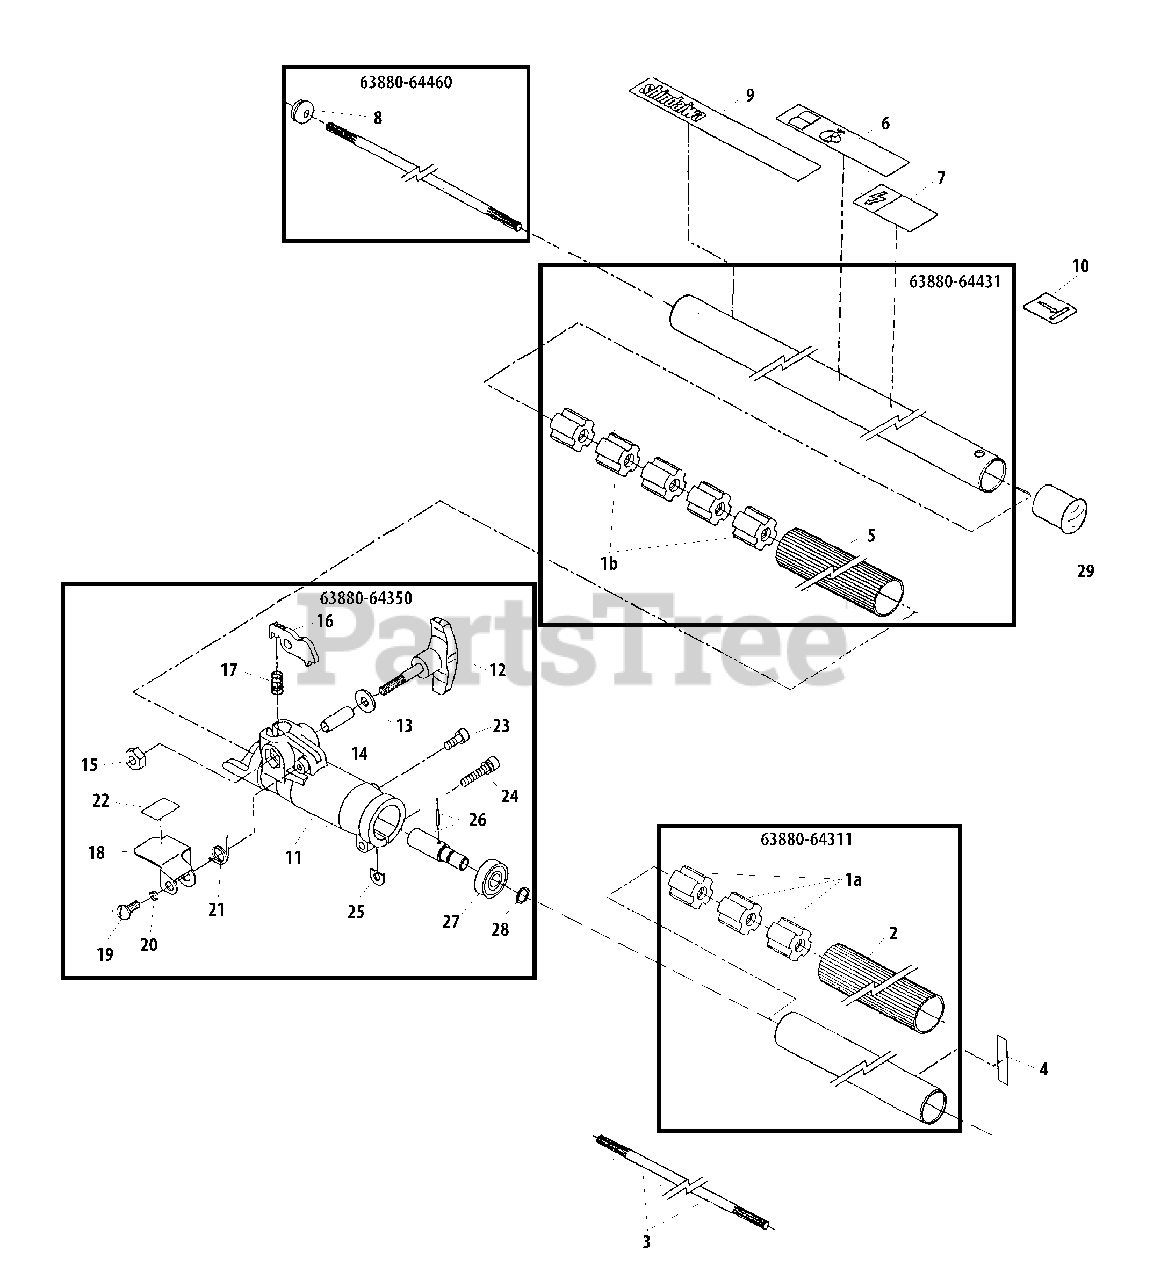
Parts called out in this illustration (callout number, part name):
3	MAINSHAFT
4	LABEL - ALIGNMENT
5	GRIP
6	LABEL, CAUTION
7	LABEL - CAUTION
8	GROMMET
9	LABEL - MODEL
10	LABEL, HIGH VOLTAGE
11	HOUSING, COUPLER
12	KNOB, COUPLER SCREW
13	WASHER 6
14	COLLAR
15	NUT 6
16	LATCH
17	SPRING
18	PROTECTOR, LATCH
19	SCREW M5×12
20	WASHER 5
21	SPRING, TORSION
22	LABEL, LATCH INSTRUCTION
23	BOLT 5×12
24	BOLT M5×25
25	D-WASHER
26	SHAFT, COUPLER
27	BEARING, BALL 609ZZ
28	RING, SNAP
29	CAP
63880-64311	MAIN PIPE ASSY
63880-64350	COUPLER ASSY
63880-64431	MAIN PIPE ASSY
63880-64460	DRIVESHAFT ASSY
